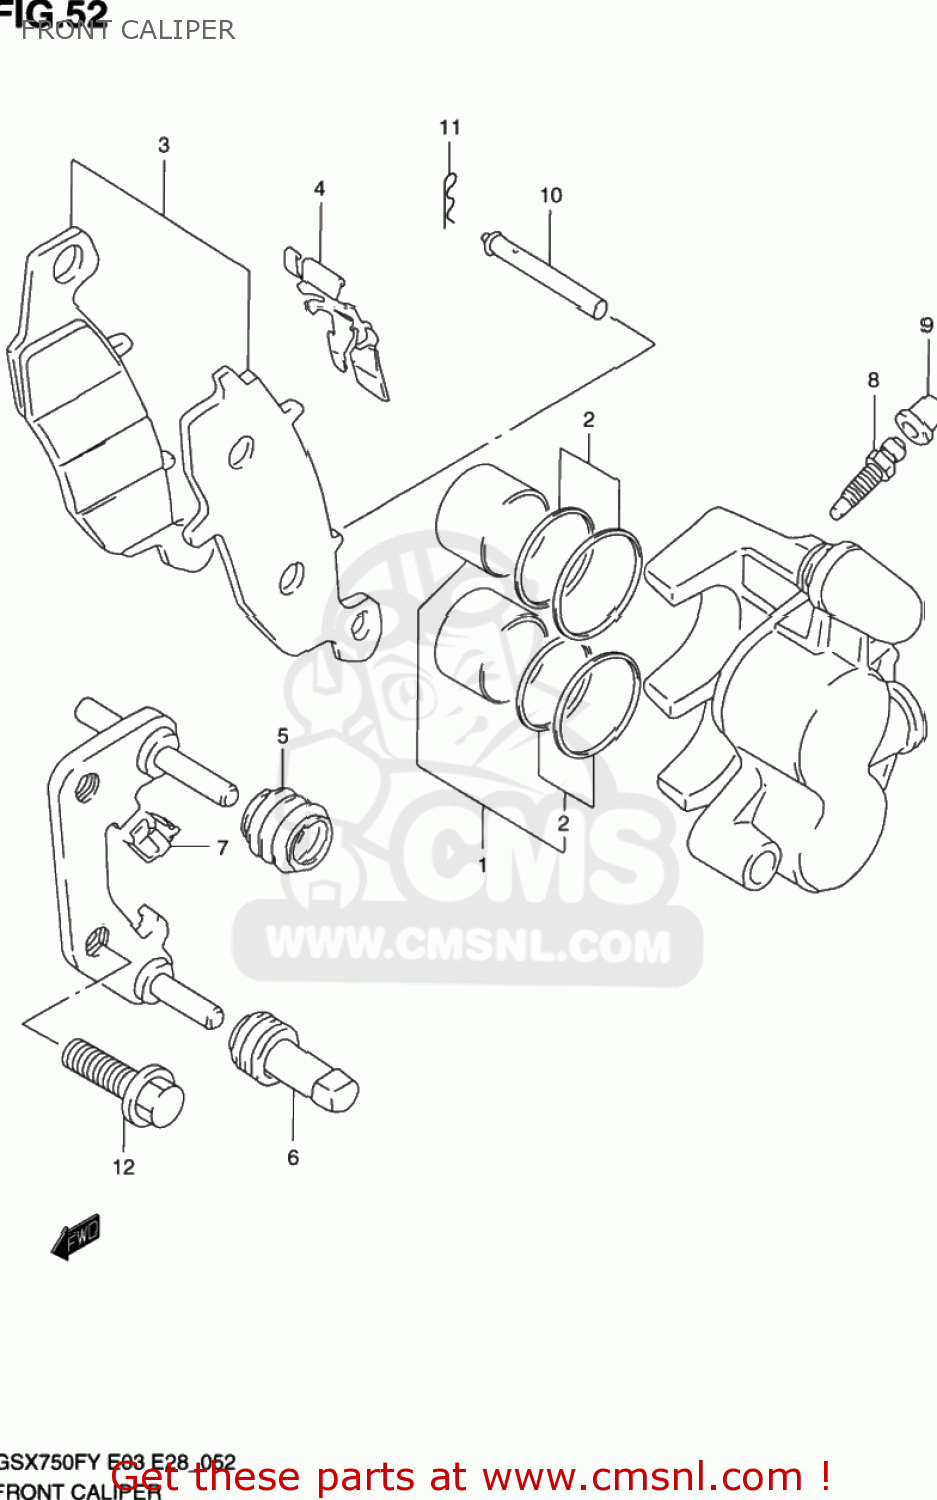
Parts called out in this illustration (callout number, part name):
1	PISTON SET
2	SEAL SET,PISTO
3	PAD SET,R (NAS)
4	SPRING,PAD,R
5	BOOT,AXLE
6	INSULATOR,AXLE
7	GUIDE,PAD
8	BLEEDER
9	CAP,BLEEDER PLUG
10	PIN,PAD
11	CLIP,PAD PIN
12	BOLT
